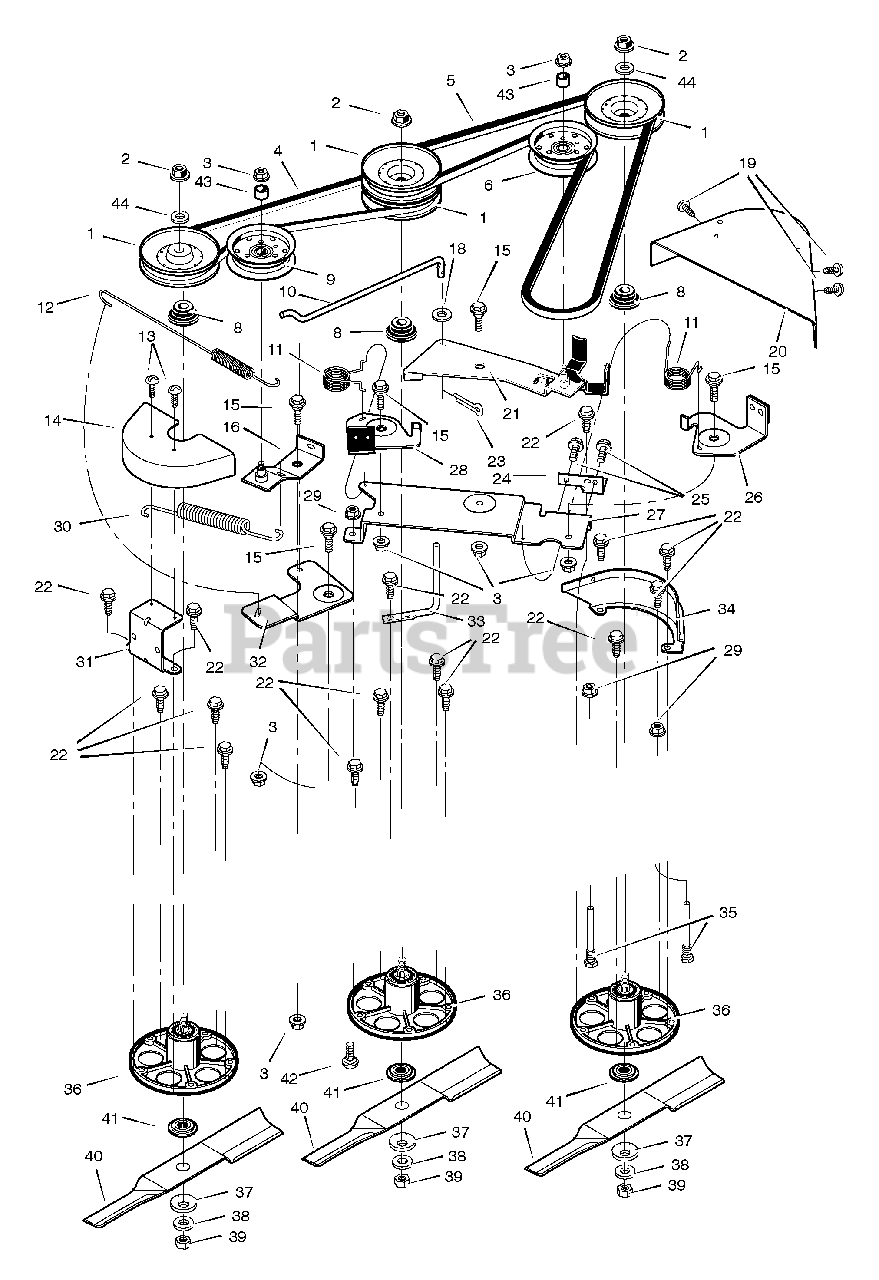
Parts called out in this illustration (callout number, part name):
1	Pulley
3	Nut
4	Belt, Secondary
5	Belt, Primary
6	Pulley, Idler
8	Spacer, Pulley
9	Pulley, Idler
10	Link, Bell Crank
13	Screw
14	Cover, Right Pulley
15	Bolt, Shoulder
16	Arm Assembly, Idler
18	Washer
20	Cover, Left Pulley
21	Arm Assembly, Idler
22	Bolt
23	Pin, Cotter
24	Bracket, Brake Plate
26	Brake Assembly, Left
27	Plate, Brake Arm
28	Brake Assembly, Center
29	Nut, Flange
31	Bracket, Co
32	Bell Crank
33	Guide, Belt
34	Bracket, Pulley Cover
35	Guide, Belt
36	Assembly, Jackshaft Housing
39	Nut, Blade
41	Adapter, Blade
42	Bolt, Carriage
44	Washer
